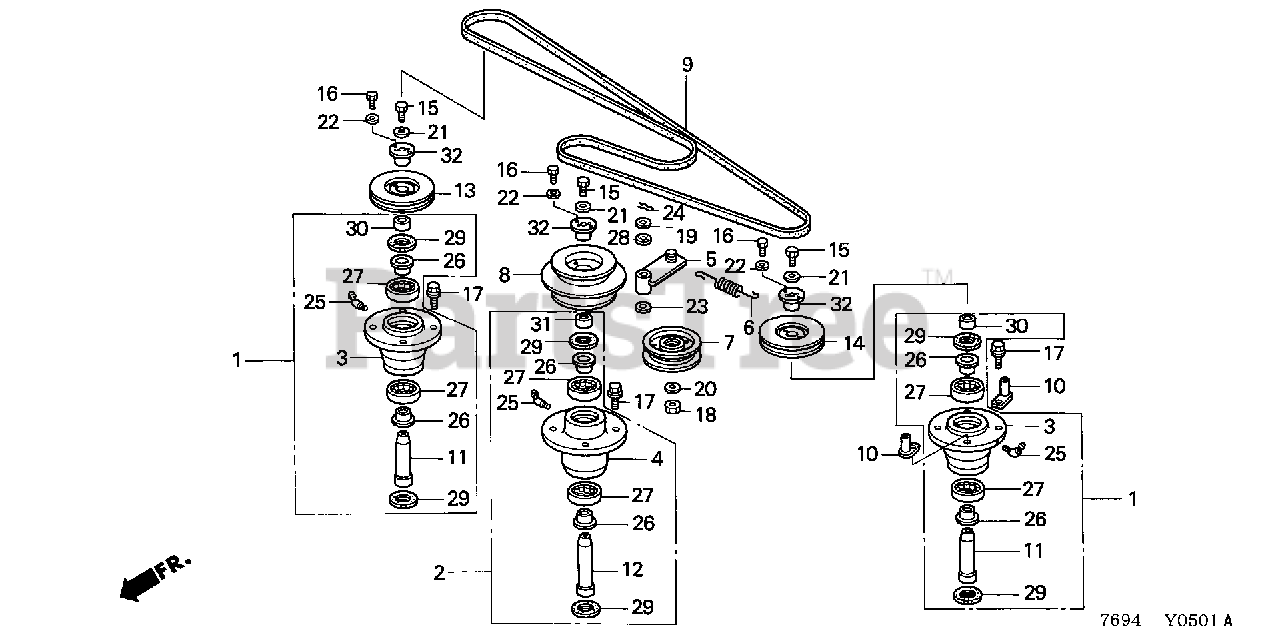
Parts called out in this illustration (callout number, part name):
1	SPINDLE ASSY. (OUTER)
2	SPINDLE ASSY., CENTER
3	HOUSING, BEARING A
4	HOUSING, BEARING B
5	ARM, TENSION (DECK)
6	SPRING, TENSIONER ARM
7	ROLLER, TENSIONER
8	PULLEY, DRIVEN
9	V-BELT, BLADE
10	STOPPER, BELT
11	SHAFT, BLADE (A)
12	SHAFT, BLADE (B)
13	PULLEY, R. DECK
14	PULLEY, L. DECK
15	BOLT (1/4 NCX1/2 HHCS)
16	BOLT (1/4 NCX1 HHCS)
17	BOLT (1/2NF HHCS)
18	NUT (5/8 NC JAM)
19	WASHER (3/4X1-1/2X18 GA)
20	WASHER (.63X.94X10 GAUGE)
21	WASHER, FLAT (1/4X7/8X7GA)
22	WASHER, LOCK (1/4)
23	WASHER (3/4X1-9/16X10GA)
24	PIN, LOCK (19MM)
25	NIPPLE, GREASE
26	CONE, BEARING
27	CUP, BEARING
28	DUST SEAL (5/8X1X1/4)
30	COLLAR, BEARING A HOUSING
31	COLLAR, BEARING B HOUSING
32	BUSH, PULLEY SETTING
